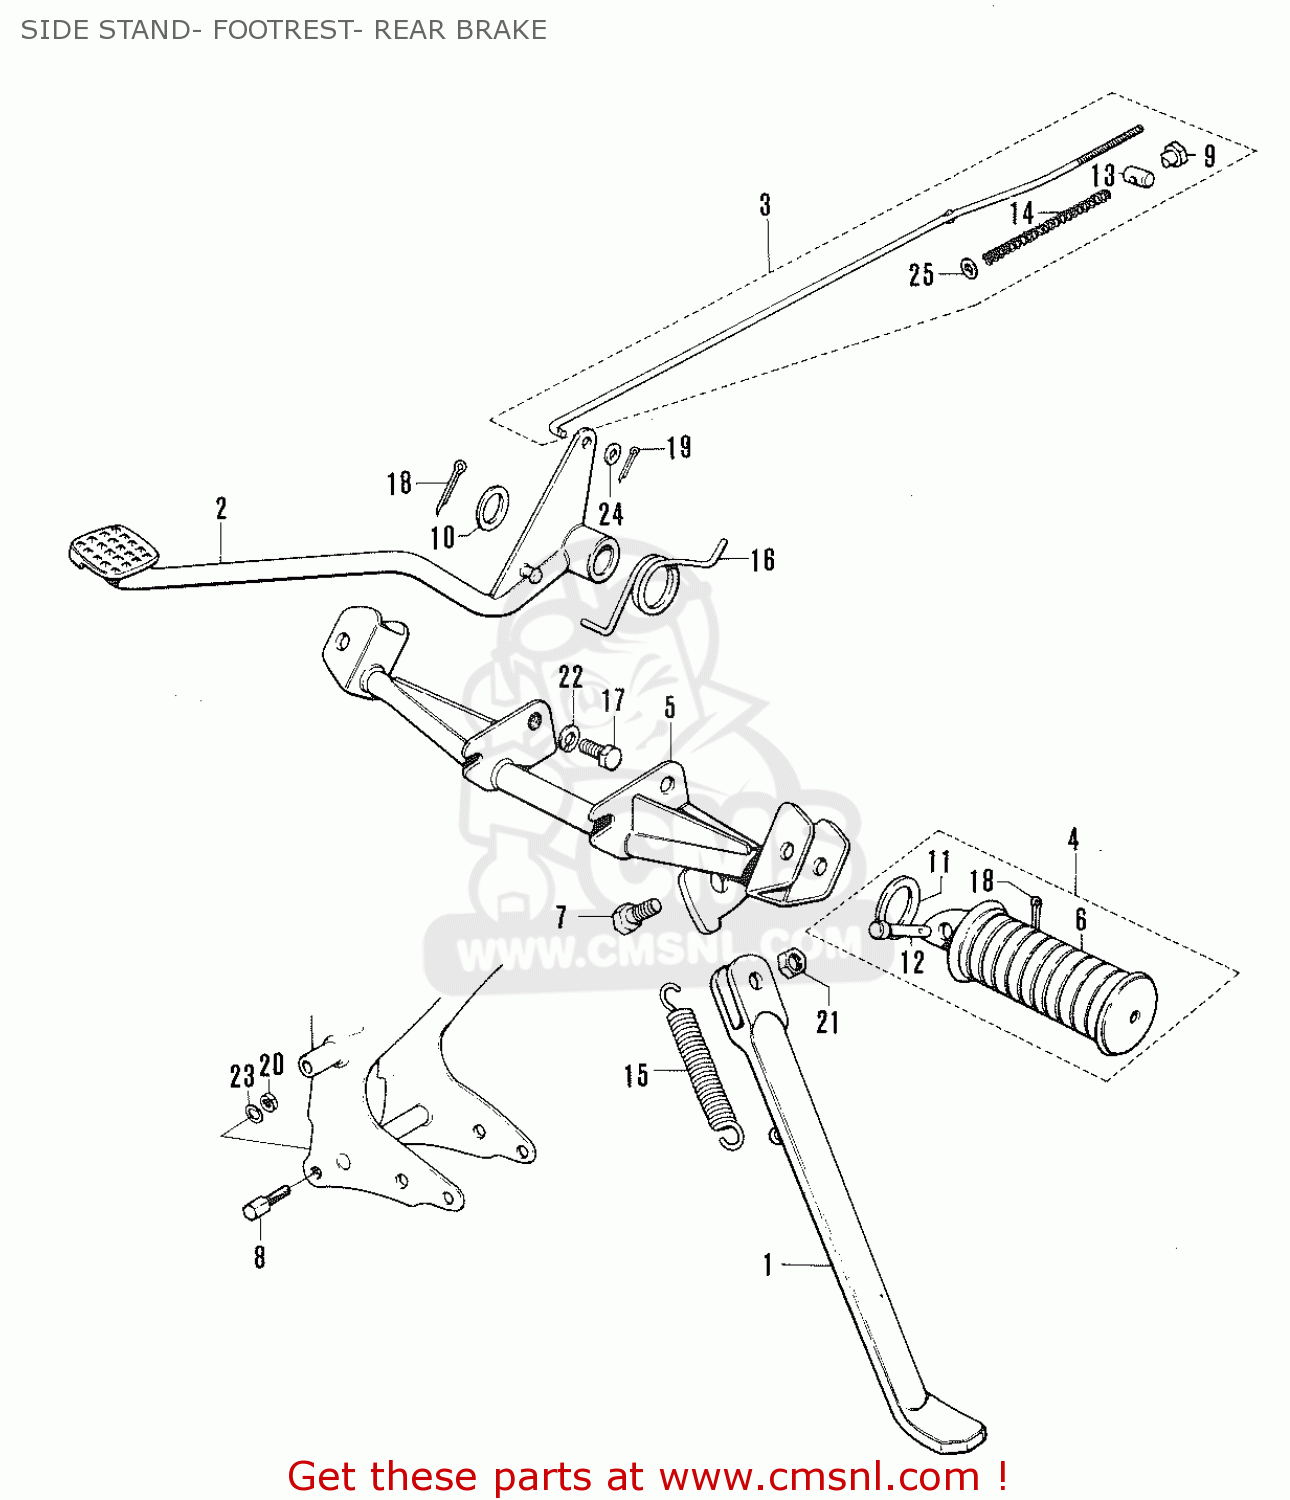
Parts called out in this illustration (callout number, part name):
1	STAND,SIDE
2	PEDAL,BRAKE
3	ROD ASSY,RR BRAKE
4	FOLDING FOOTREST RUBBER ASS'Y
5	BAR,FRONT FOOTREST
6	RUBBER,FRONT FOOTREST
7	BOLT
8	BOLT
9	NUT
10	WASHER(15.5X26X2.3)
11	WASHER
12	PIN
13	PIN(11X18)
14	SPRING
15	SPRING
16	SPRING
17	BOLT
18	PIN
19	PIN
20	NUT
21	NUT
22	LOCK WASHER
23	LOCK WASHER
24	WASHER
25	WASHER
